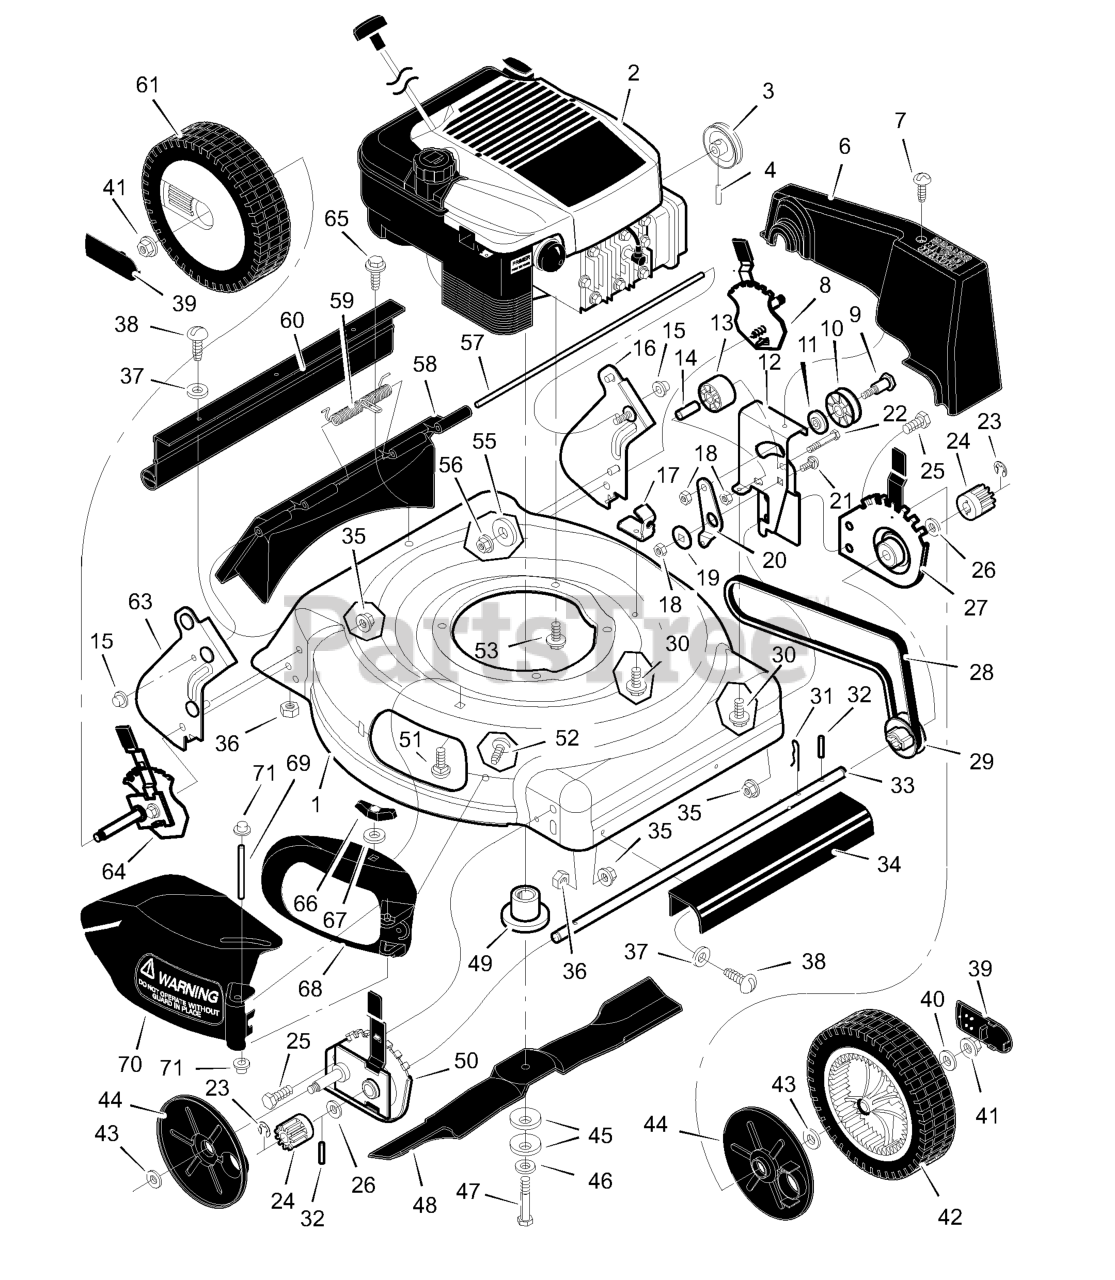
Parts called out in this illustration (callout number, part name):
1	Housing
2	Engine
3	Pulley, Engine
4	Pin, Spring
6	Cover, Belt (Black)
8	Adjuster, Left Height
9	Bolt, Shoulder
12	Bracket, Idler Support
13	Pulley, Idler
14	Bearing
15	Nut, Push
16	Bracket, Left Handle
17	Bracket, Cable
18	Nut, Hex
20	Arm, Idler
21	Bolt, Carriage
22	Bolt, Shoulder
24	Gear, Pinion
25	Bolt
27	Adjuster, Left Frt. Height
29	Pulley, Axle
31	Pin, Hair
32	Pin, Spring
34	Cover, Axle (Black)
35	Nut, Flange
36	Nut, Hex
39	Cap, Hub
40	Washer
41	Nut, Flange
42	Wheel, Drive
44	Cover, Dust
45	Washer, Belleville
49	Adapter, Blade
50	Adjuster, Right Frt. Height
51	Bolt, Carriage
53	Bolt, Engine
55	Washer
56	Nut, Flange
57	Rod, Pivot
58	Door, Rear (Black)
60	Deflector, Rear
61	Wheel, Rear
63	Bracket, Right Handle
64	Adjuster, Right Height
66	Wingnut
67	Retainer, Push
68	Bezel (Black)
69	Pin, Pivot
70	Deflector, Chute (Black)
71	Push On Cap
